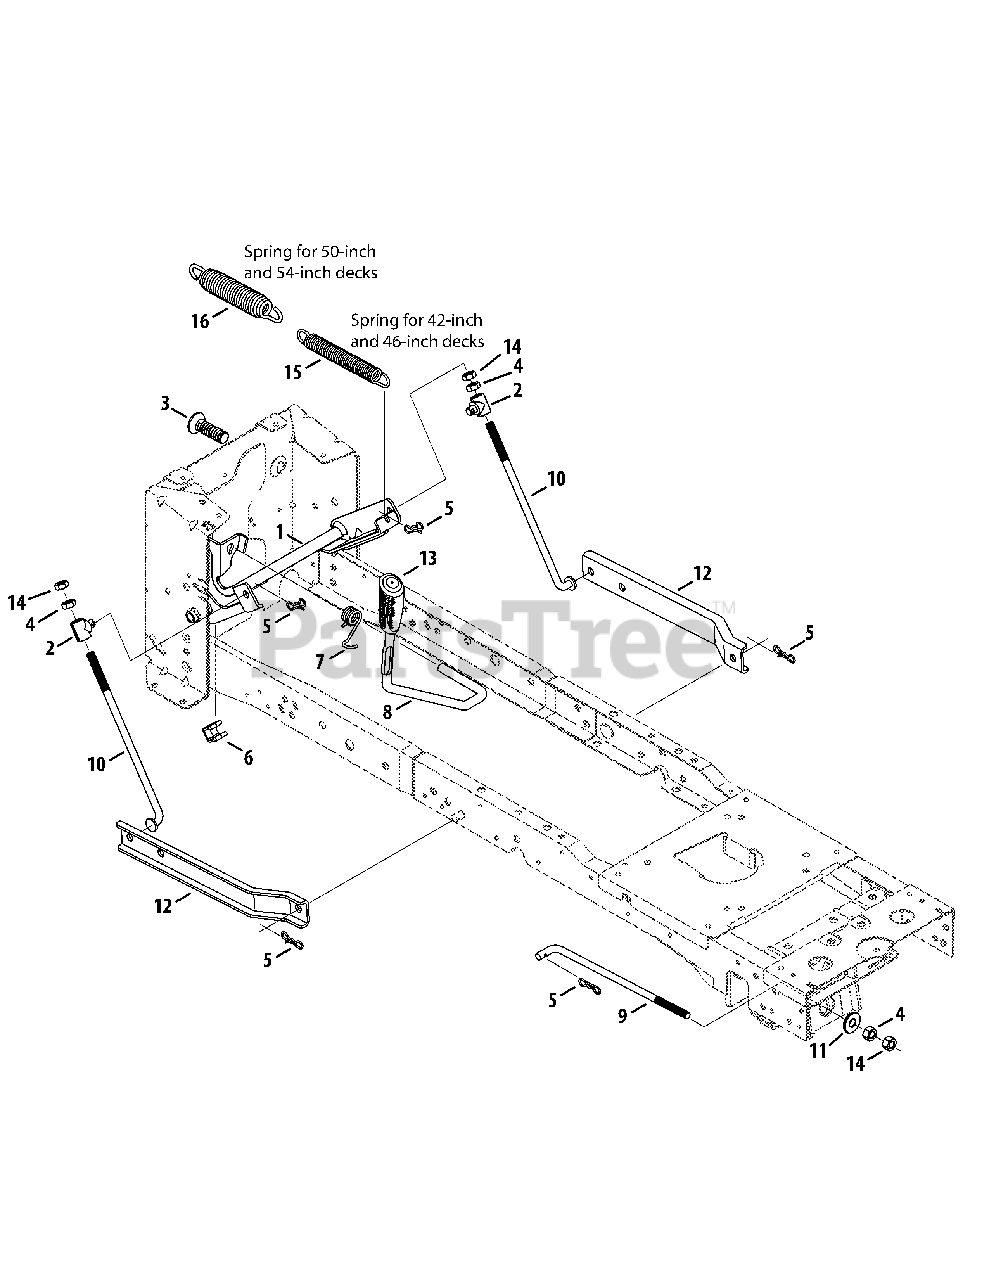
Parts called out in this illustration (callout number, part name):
1	Shaft Assembly, Lift
2	Ferrule, .510 x .496
3	Spring Insert
4	Nut, Jam, 1/2-13
5	Bow-Tie Cotter Pin
6	Spacer, .76 ID x .93 LG
7	Torsion Spring
8	Deck Lift Handle
9	Deck Lift Rod
10	Lift Adjustment Link
11	Pivot Cup
14	Hex Lock Nut, 1/2-13
15	Lift Assist Spring, (42"/46")
16	Lift Assist Spring, (50"/54")
